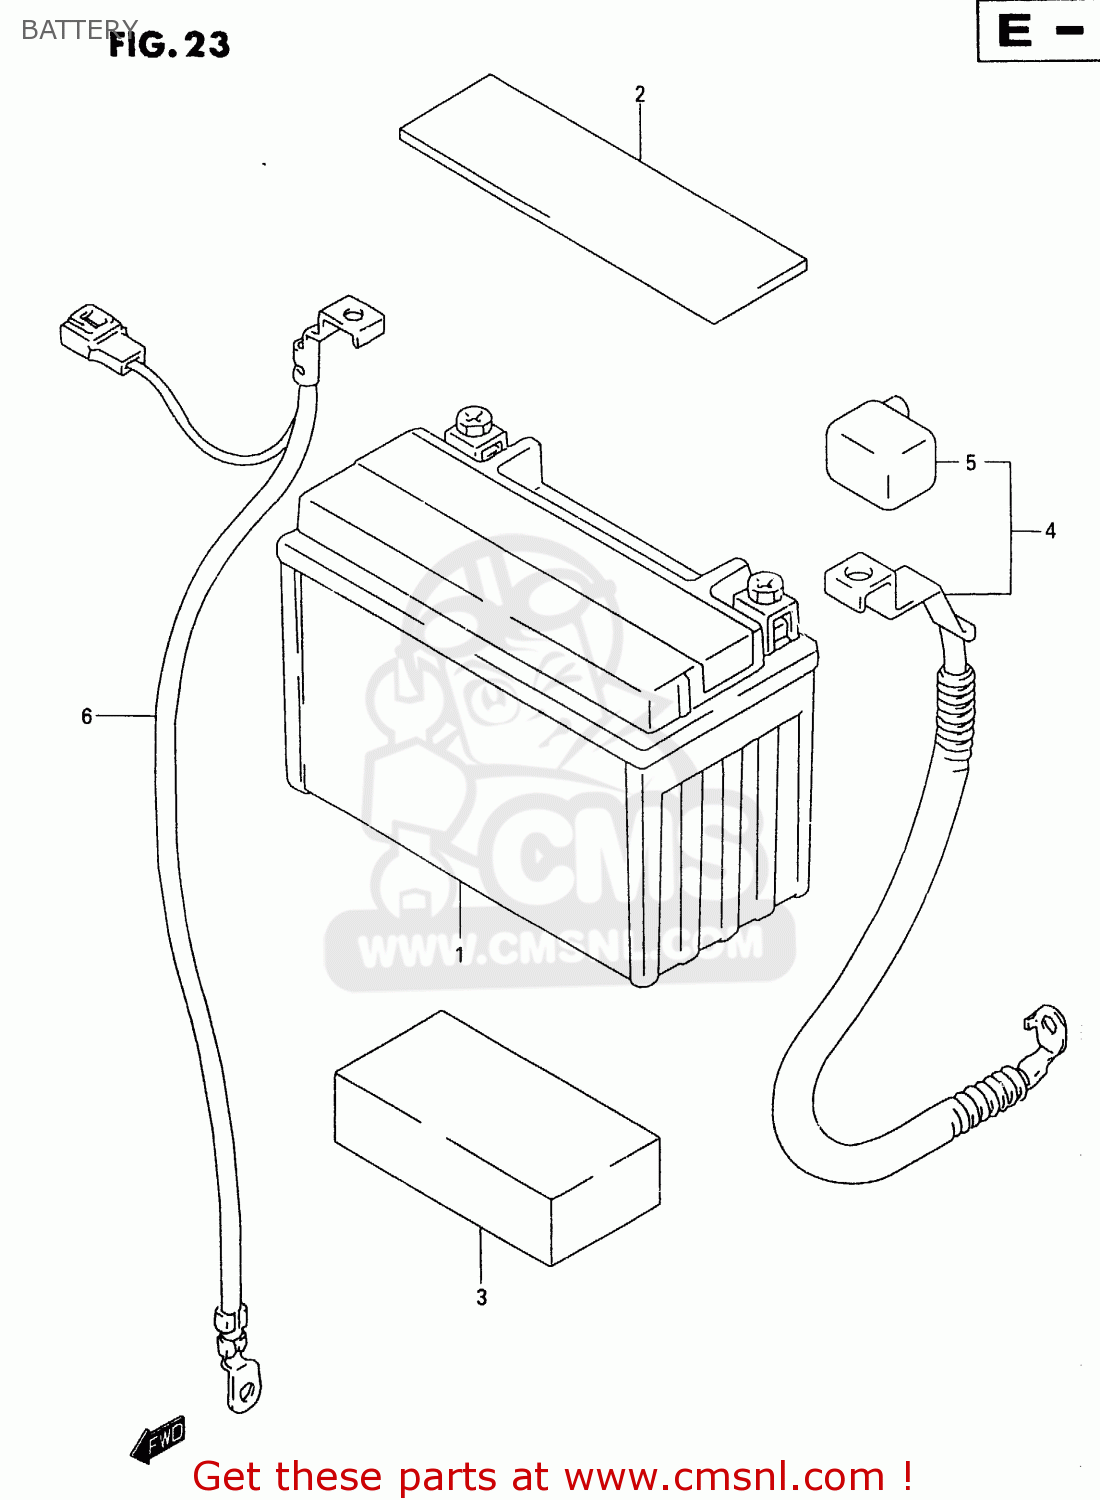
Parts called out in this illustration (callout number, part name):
1	BATTERY ASSY(YTX9-BS,12V8AH)
2	PROTECTOR(170X95X3.0)
3	PROTECTOR(20X50X8)
4	WIRE,BATTERY PLUS LEAD
5	CAP,BATTERY PLUS
6	WIRE,BATTERY MINUS
